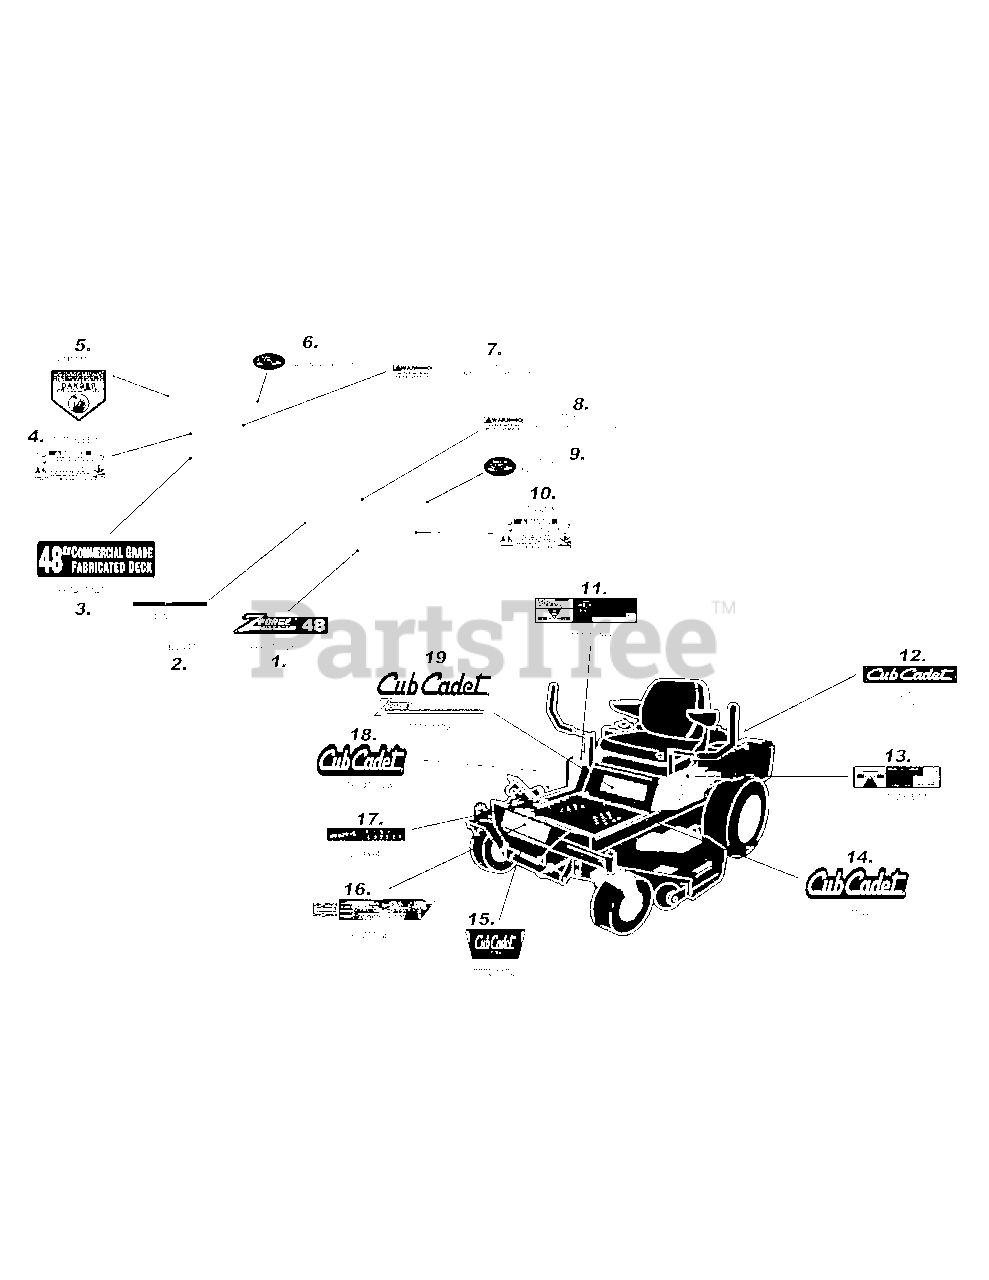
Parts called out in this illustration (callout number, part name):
1	LABEL - FRONT Z-FORCE 48
2	DECAL - 50' DECK BELT RT Z-FORCE
3	LABEL - 48" FAB Z FORCE
4	LABEL - RZT DECK WARNG STRAIGHT
5	LABEL - HANDS & FEET WALKBEHINDS
6	LABEL - DECK WASH
7	DECAL - WARNING 50' DECK Z-FORCE
8	DECAL - WARNING 50' DECK Z-FORCE
9	LABEL - DECK WASH
10	LABEL - RZT DECK WARNG STRAIGHT
11	LABEL - CONTROL
12	LABEL - FRAME REARZ FORCE
13	LABEL - SAFETY Z FORCE
14	LABEL - SIDE FRAMELOGO Z FORCE
15	LABEL - FRAME
16	LABEL - Z FORCE
17	LABEL - DECK HEIGHT ADJ
18	LABEL - Z FORCE
19	LABEL - Z-FORCE BELOW SEAT
